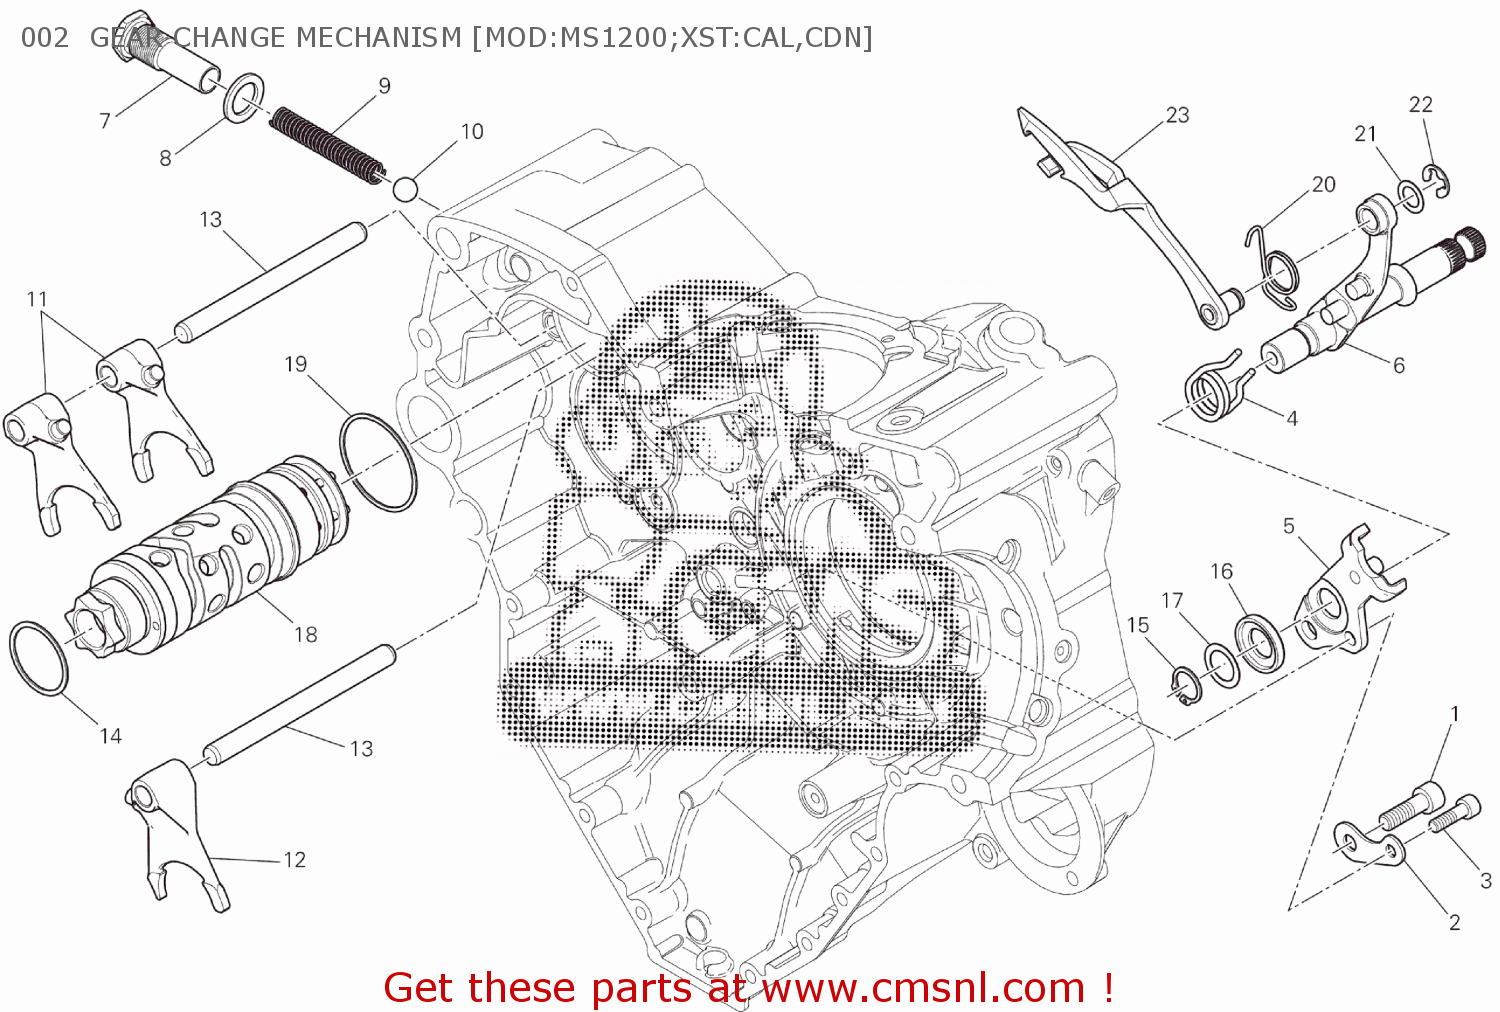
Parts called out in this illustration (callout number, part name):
1	SCREW
2	SPACER
3	SCREW
4	SPRING, SHIFT RETURN
5	STOPPER PLATE
6	GEAR SELECTOR SHAFT
7	SCREW M16X1.5
8	GASKET 16.2X24X2
9	GEAR SELECTOR SPRING
10	BALL 11MM
11	GEAR SELECTOR FORK,1ST/4TH-2ND/3RD
12	FORK-SHIFT, 5TH&6TH
13	FORK PIN
14	THRUST WASHER 1 MM
15	CIRCLIP 15 DIN 471
16	CENTERING RING
17	THRUST WASHER 15.5X22X0.5
18	COMPLETE GEARBOX DRUM
19	THRUST WASHER 45.2X49X0.9
20	RETURN SPRING
21	THRUST WASHER 10.5X16X0.5
22	SPRING RING
23	CONTROL FORK
